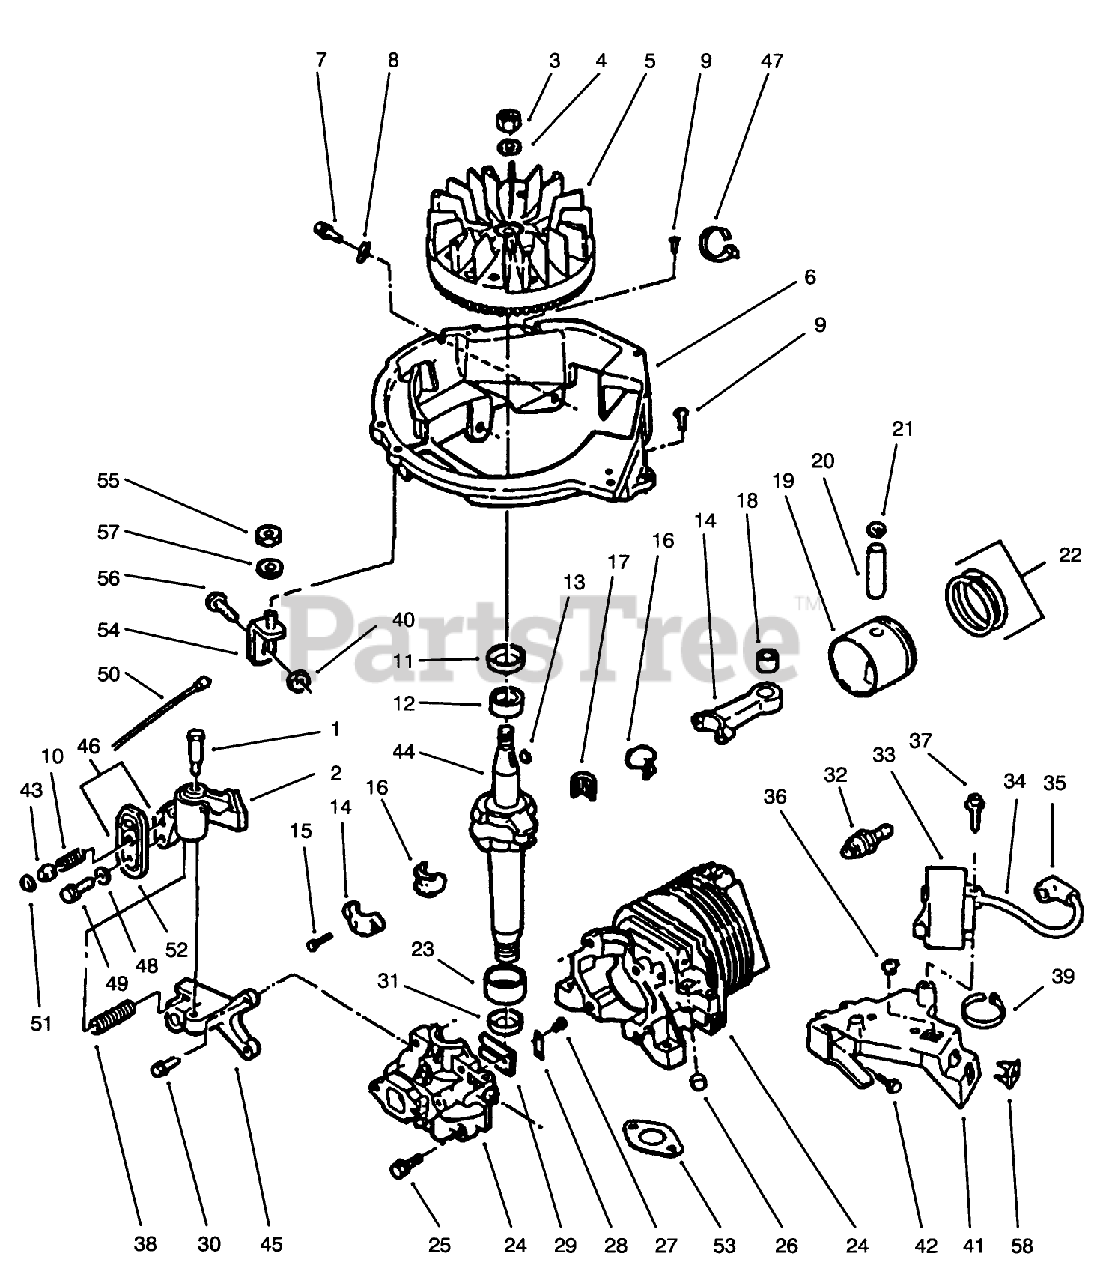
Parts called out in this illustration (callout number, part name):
1	SCREW-SHOULDER
5	FLYWHEEL ASSY F
6	BASE SHROUD F
7	SCREW-SEMS
9	SCREW F
11	SEAL-OIL
12	BEARING V
15	SCREW-HSH
16	LINER ASM
17	BEARING-NEEDLE
18	BEARING XEV
21	RING-RETAINING
23	BEARING V
25	SCREW-H.W.HD. F
26	PLUG-CORE VF
27	SCREW-HH
28	PLATE-BACKUP, REED
31	SEAL-OIL
32	SPARK PLUG
33	C. D. Ignition Module Lead Assy. (Inc. 34-35)
34	HT LEAD&COVER XEV
35	COVER & TERM. AY S
36	NUT-CLIP
38	SPRING-BRAKE
39	TIE-CABLE
40	NUT-LOCK F
41	C.D. BRKT F
42	SCREW F
43	ACTUATOR-LEVER, BRAKE
45	BRACKET-BRAKE F
50	WIRE LEAD AY F
51	RETAINER S
54	BRACE AY F
55	LOCKNUT E
58	NUT-SPEED
